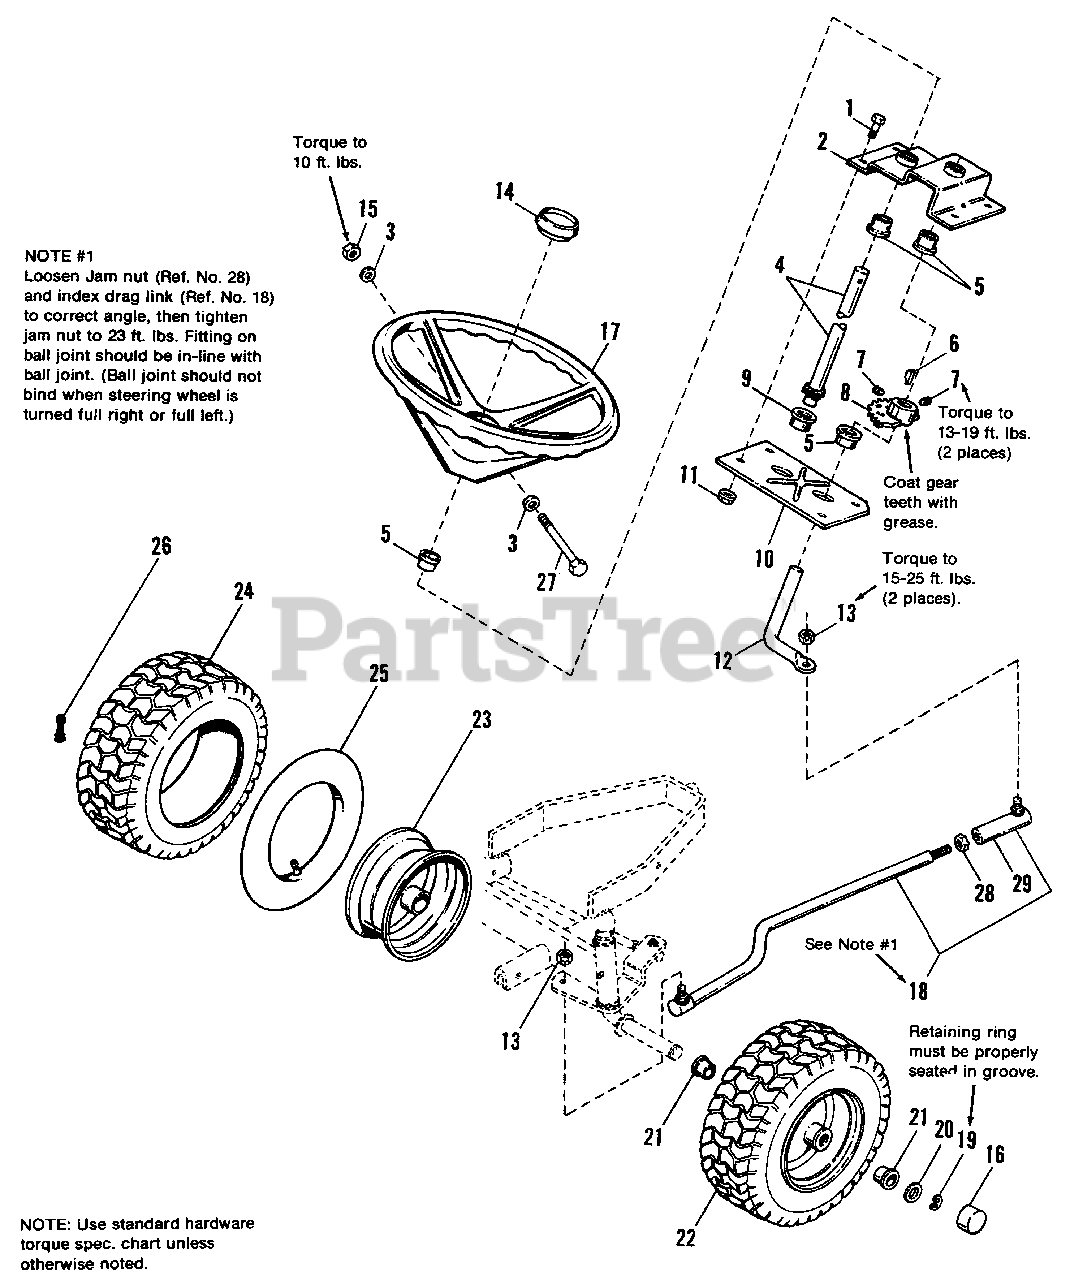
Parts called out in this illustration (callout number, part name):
1	CAPSCREW, 5/16-18 x 3/4
2	PLATE, Steering
3	WASHER, Plain, 5/16
4	SHAFT ASSY., Steering
7	SETSCREW, 5/16-18 x 1/2
8	GEAR, Steering
10	PLATE, Steering
11	LOCKNUT, Hex, Flange, 5/16-18
12	ROD, Steering
13	NUT, Special
14	CAP, Steering Wheel
15	LOCKNUT, 5/16-18
16	CAP, Hub, Thrd.
17	WHEEL, Steering
18	LINK, Drag (Includes Ref. No. 28 & 29)
19	E-RING, Ext., 3/4
22	WHEEL & TIRE ASSY., 15 x 6.00-6 (Includes Ref. No. 21, 23, 24, 25 & 26)
23	WHEEL
24	TIRE, 15 x 6.00-6 (Carlisle)
25	TUBE, 4.10/3.50-6
26	STEM, Valve & Cap
27	BOLT, Hex 5/16-18 x 3 1/2
